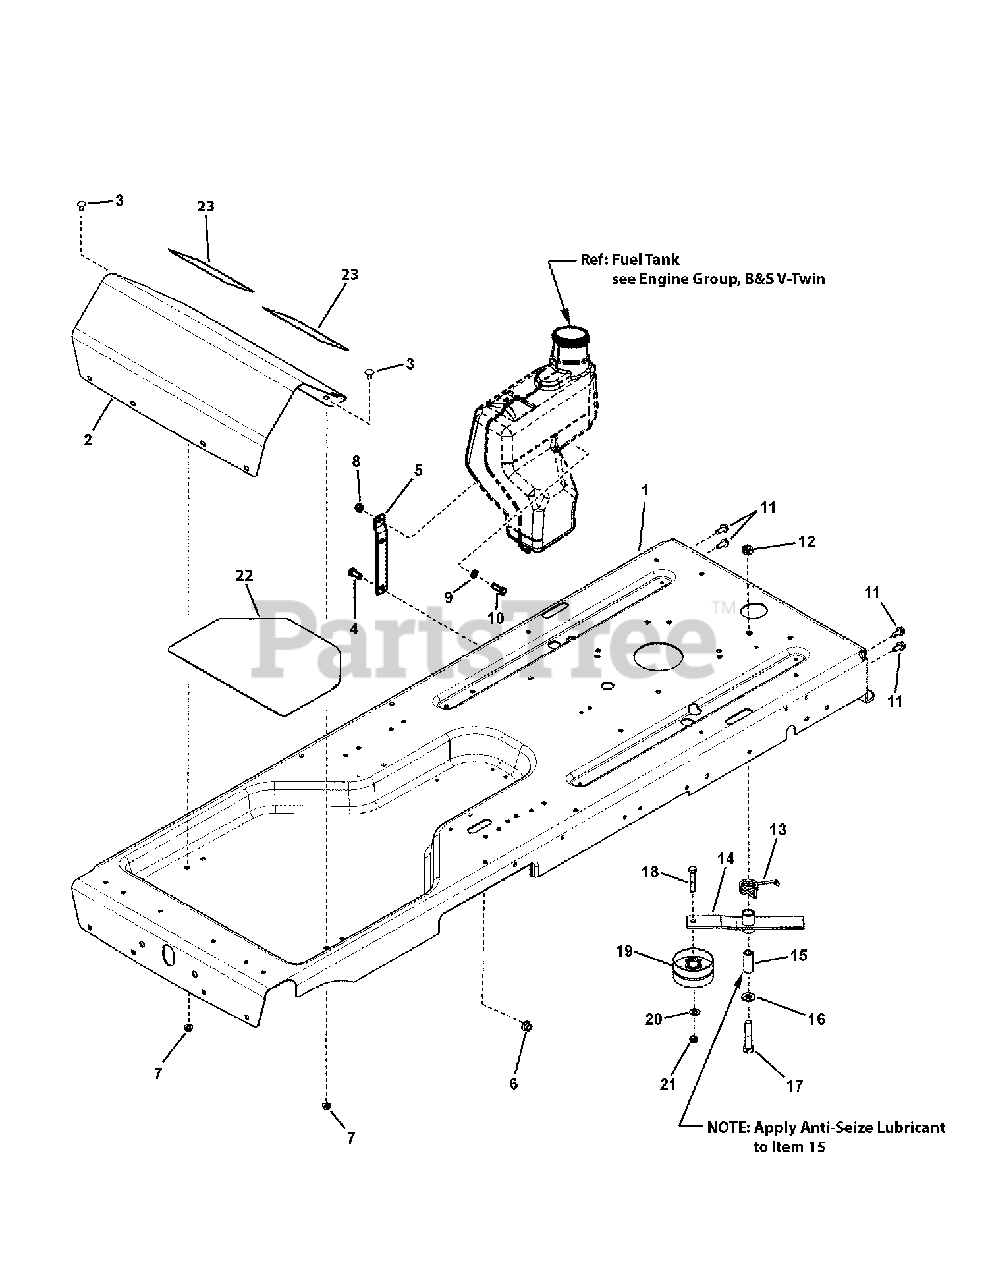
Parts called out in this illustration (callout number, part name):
1	FRAME, RZT (Orange)
1	FRAME, RZT (Red)
2	FOOTREST (Orange)
2	FOOTREST (Red)
3	BOLT, 5/16-18 x 5/8" Round Head Short Square Neck Carriage, GR 5
4	SCREW, 3/8-16 x 3/4" Hex Head Cap, GR 5 ZP
5	BRACKET, Support, Fuel Tank
6	NUT, 3/8-16 Hex Flange lock, GR F, BZ
7	NUT, 5/16-18, Hex Flange Lock, GR 5
8	NUT 5/16-18- Nyloc, YZ
9	WASHER, .34 x .62 x 16 Ga, Flat
10	SCREW, 5/16-18 x 1" Hex Head Cap, GR 5, YZ
11	SCREW, 5/16-18 x 3/4" Hex Washer Self-Tap, YZ
12	NUT, 1/2-13 Hex Center Lock, GR 5, YZ
13	SPRING, Torsion, RH Wind
14	WELDMENT, Hydro Idler MY08
15	SPACER, Hydro Idler
16	WASHER, .531 x 1.062 x .121, Flat, YZ (SAE)
17	SCREW, 1/2-13 x 2-1/2", Hex Head Cap, GR 5 (Black Phosphate)
18	SCREW, 3/8-16 x 2" Hex Head Cap, GR 5, YZ
19	IDLER, 3.25" OD x .391 ID x 1.63, Backside
20	WASHER, 3/8" Flat (SAE)
21	NUT, 3/8-16 Hex Center Lock, YZ
22	MAT, Floor Pan, RZT
23	PAD, Foot, Wide, RER
